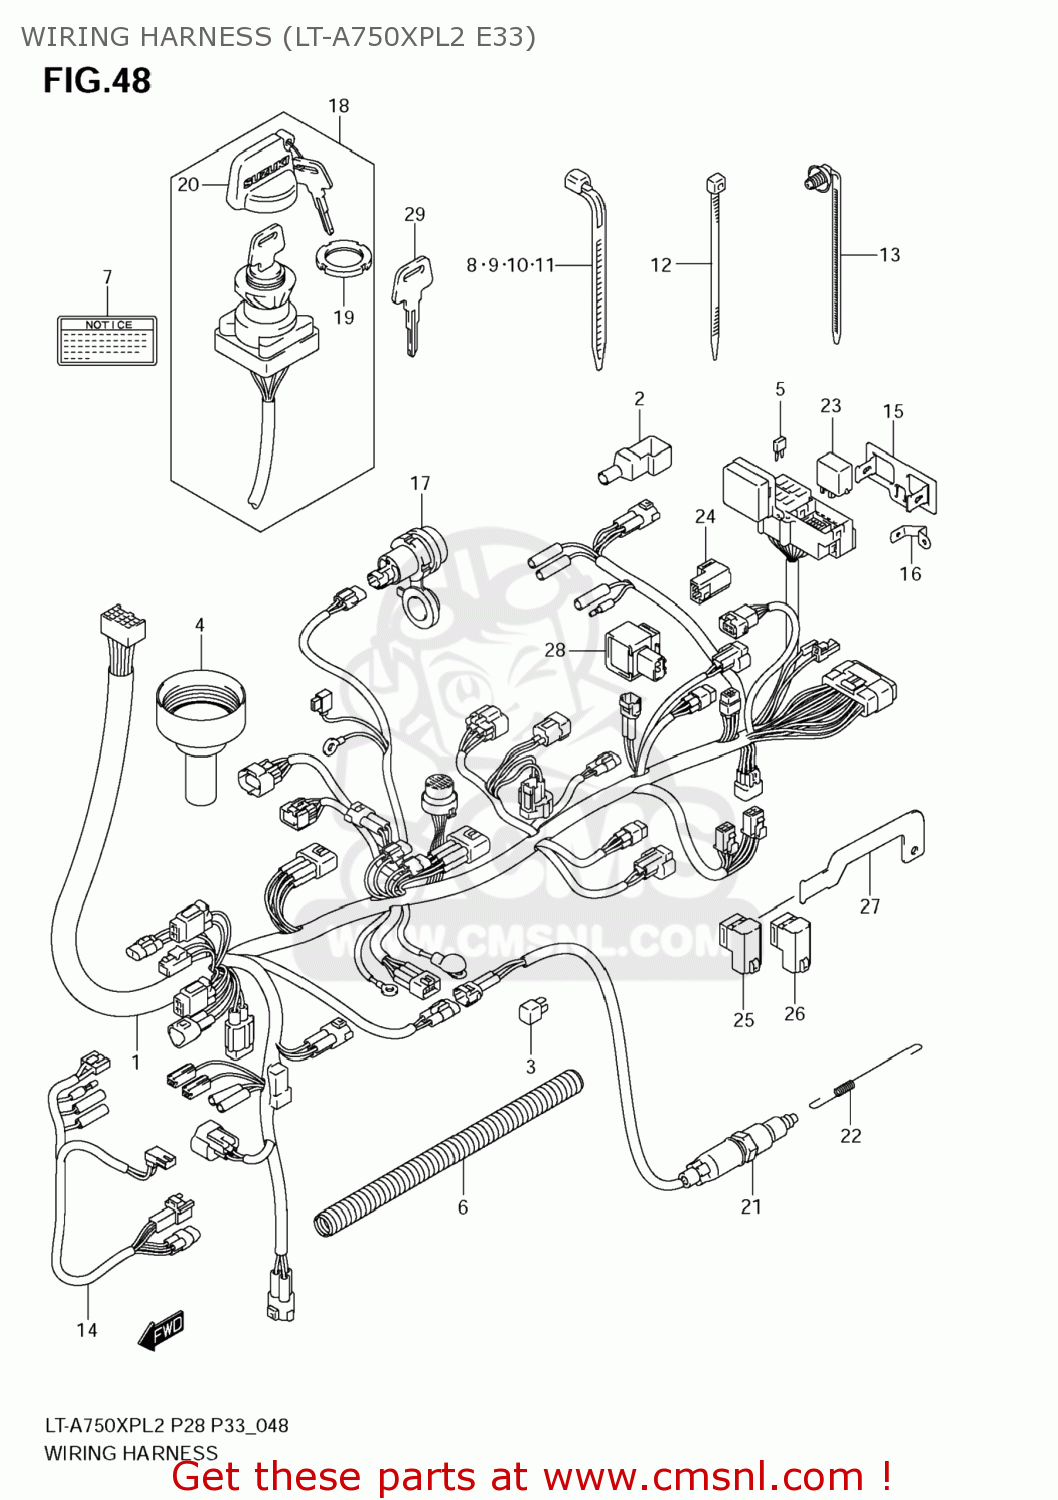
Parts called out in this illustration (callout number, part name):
1	HARNESS,WIRING
2	COVER,CONNECTOR
3	RECTIFIER ASSY
4	COVER,SPEED
5	FUSE(10A)
6	GUIDE,WIRING HARNESS
7	LABEL,POWER SOURCE TERMINAL
8	CLAMP(L:95)
9	CLAMP(L:125)
10	CLAMP(L:190)
11	CLAMP(L:235)
12	CLAMP(L:145)
13	CLAMP(L:154)
14	WIRE,FR BRAKE SW LEAD
15	BRACKET,FUSE BOX
16	BRACKET,FUSE
17	TERMINAL,POWER SOURCE
18	SWITCH ASSY,IGNITION
19	NUT,IGNITION SWITCH
20	MASCOT,KEY
21	SWITCH ASSY,STOP LAMP
22	SPRING
23	RELAY,NEUTRAL START
24	RELAY ASSY,FUEL PUMP
25	RELAY ASSY,FUEL PUMP
26	RELAY ASSY,FUEL PUMP
27	BRACKET,RELAY
28	RELAY ASSY,DRIVE
29	KEY,BLANK(TYPE:C)
